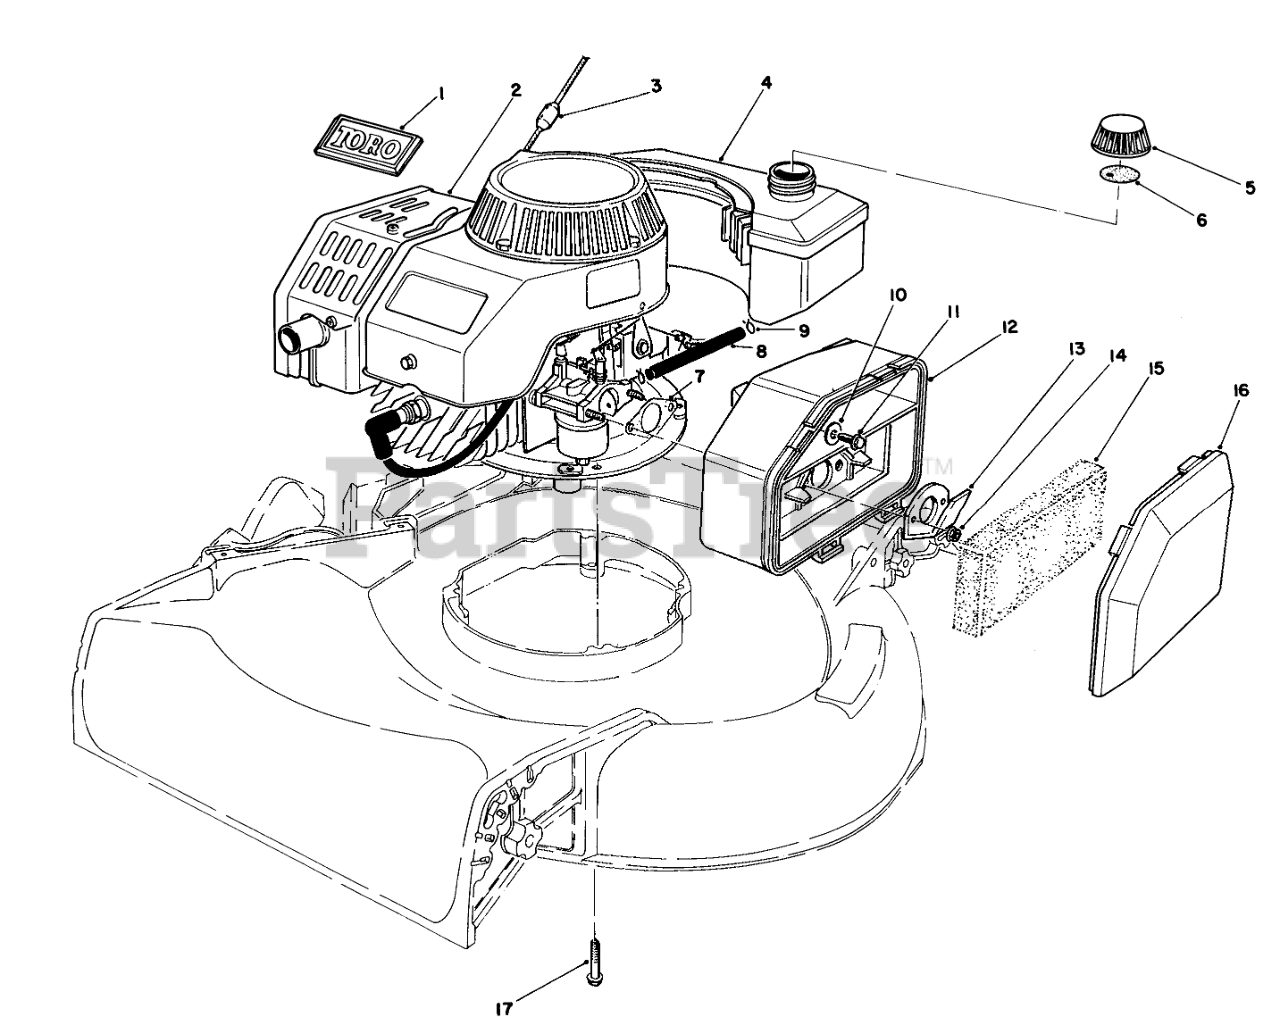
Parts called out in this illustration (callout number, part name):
1	TORO LOGO PLT
2	Engine
3	STOP-ROPE
4	Fuel Tank Assembly
5	Gas Cap Assy. (Incl. Ref. #6)
6	GAS CAP GASKET
7	GASKET-AIR CLEANER
8	FUEL LINE
9	CLAMP-HOSE
10	WASHER-FLAT
11	SCREW-HH
12	AIR CLEANER
13	SPIT BACK DEFLECTOR
14	NUT-LOCK
15	FILTER
16	AIR CLEANER COVER
17	FLG SCREW,3/8-16X2.000
